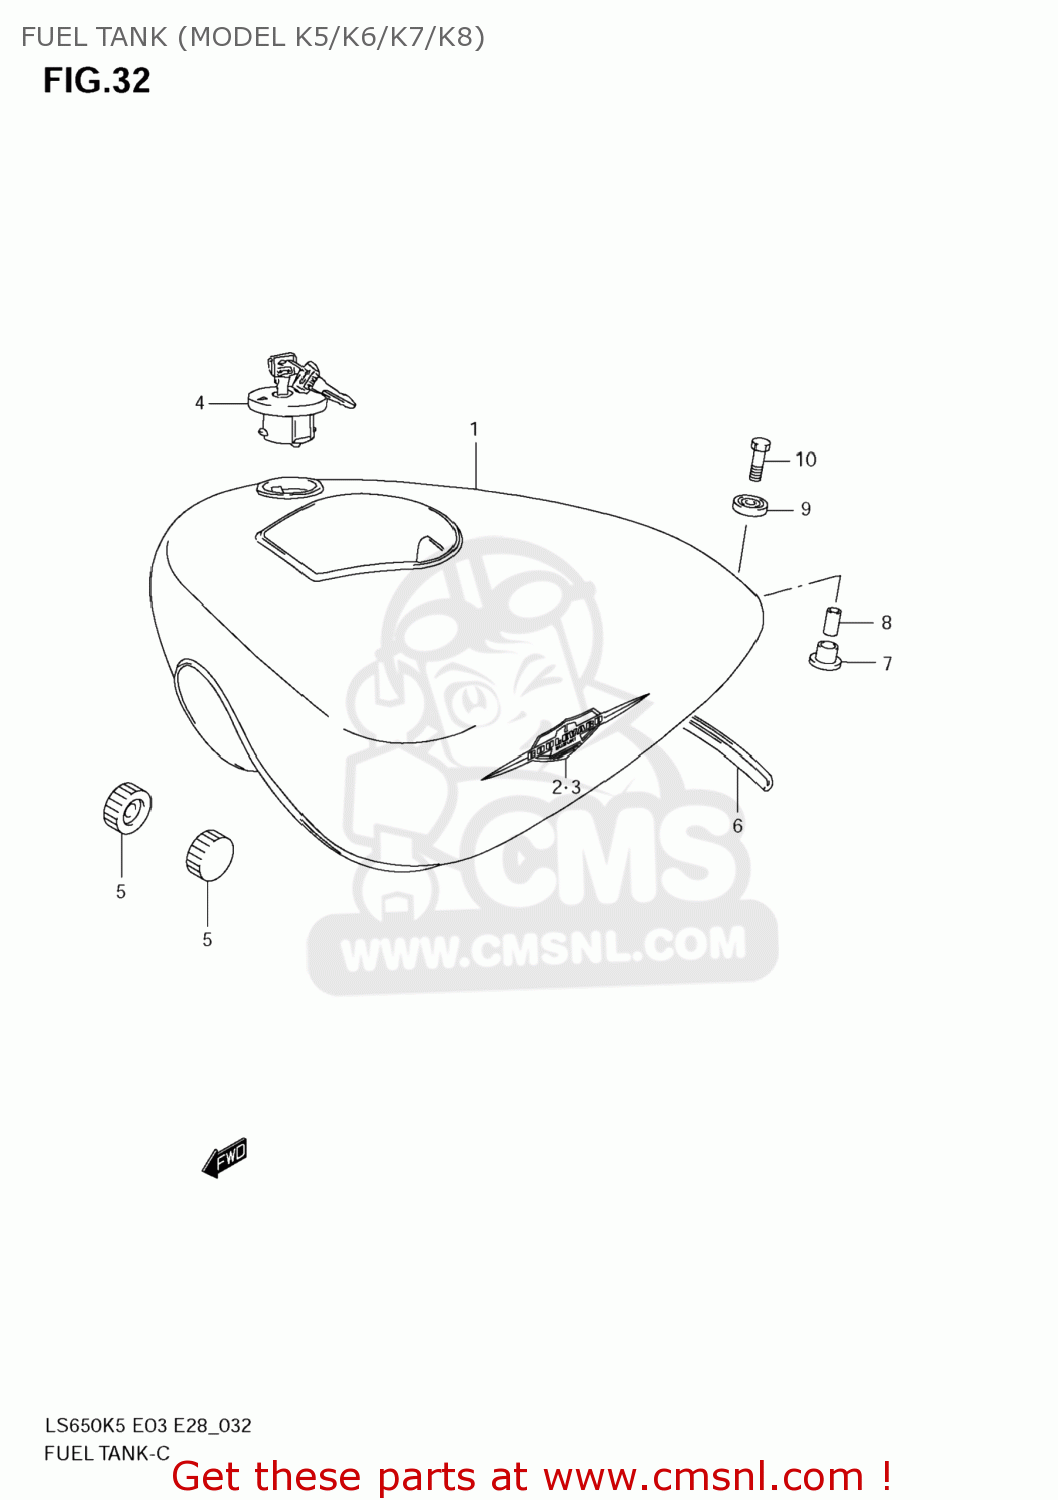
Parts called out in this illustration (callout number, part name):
1	TANK ASSY,FUEL(SILVER)
2	EMBLEM, RH
3	EMBLEM, LH
4	CAP SET,FUEL TANK
5	CUSHION
6	MOLDING,FUEL TANK RR
7	CUSHION
8	SPACER(6.5X9X18)
9	CUSHION
10	BOLT
